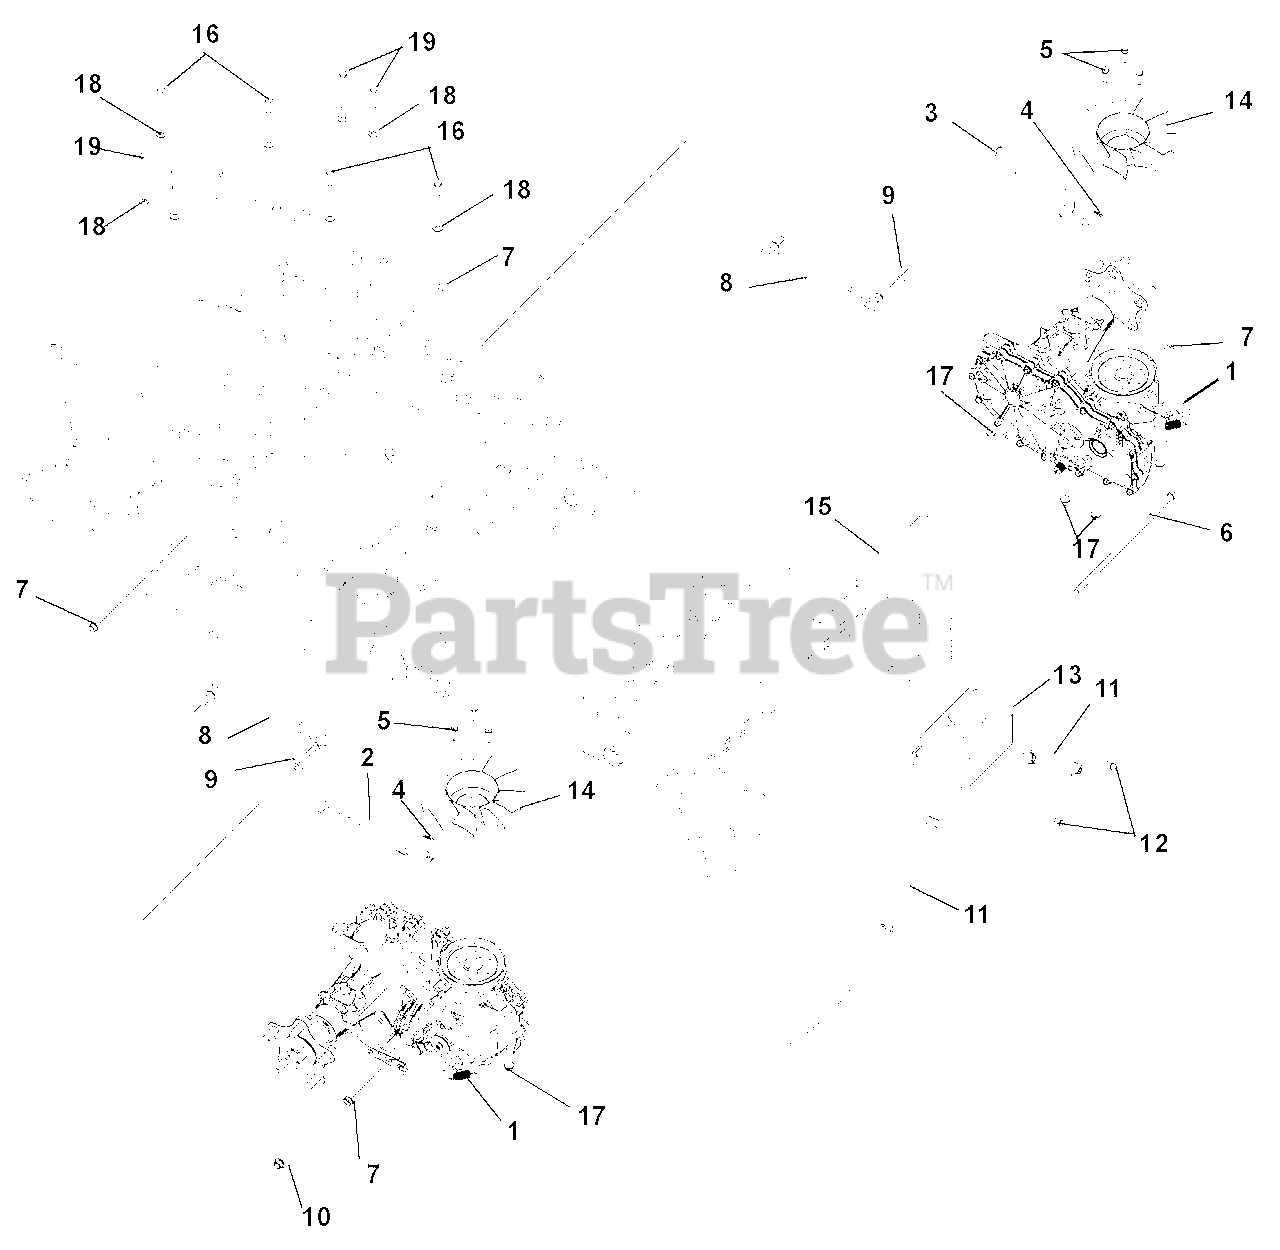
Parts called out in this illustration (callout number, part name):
1	Transaxle, 3100 Series- Left Hand (page 14)
2	Right Hand Dump Valve Lever- Black
3	Left Hand Dump Valve Lever-Black
4	Pin-Hair-Internal .06 x .18 x .77
5	Screw, Tapping .25-20 x 1.00 Hex Washer Head Thread
6	Bolt, Hex .38-16 x 11.00 Grade 5
7	Nut, Flange Patch M8-1.25
9	Washer, Flat-Steel .38 x .87 x .179
10	Nut, .38-16 Nyloc Flange
11	Assembly, Hydro Overflow Tank Hose
12	Screw, Tapping .25-20 x .50 Hex Washer Head Thread
13	Tank, Expansion
14	Fan, Cooling
15	Spacer, .38 ID x 5/8 OD x 7.72
16	Bolt, Hex .31-18 x 2.50 Grade 5
17	Nut, Nyloc Flange .312-18
18	Washer, Flat-Steel .344 x .688 x .065
19	Bolt, Hex .31-18 x 3.00 Grade 5
